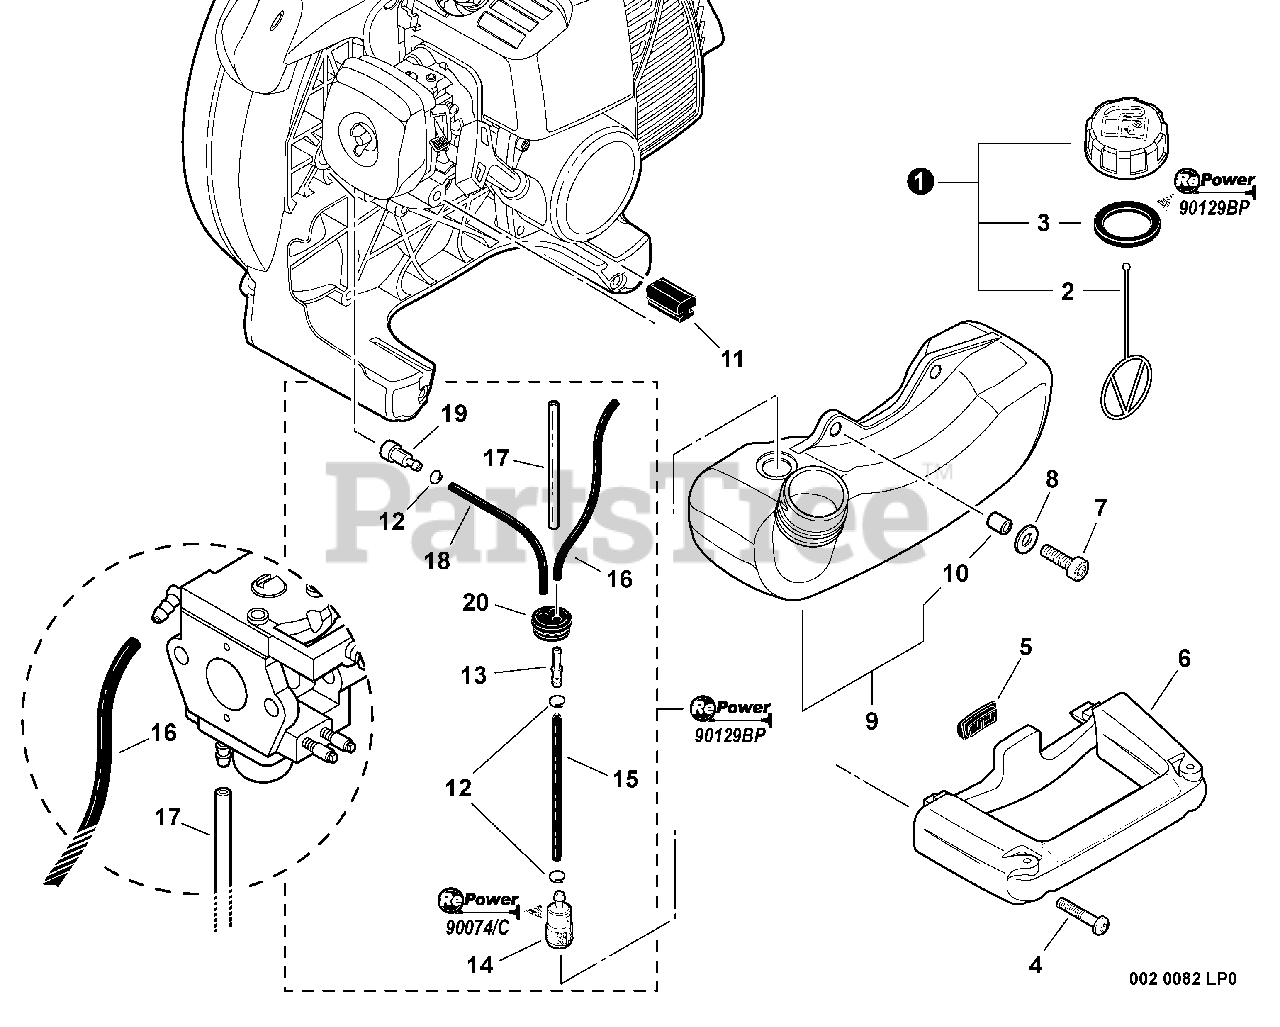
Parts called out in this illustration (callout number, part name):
1	CAP ASSY, FUEL
2	CONNECTOR, CAP L= 100 MM
3	GASKET, FUEL CAP
4	BOLT, TORX 5×25
5	CUSHION
6	HANDLE, REAR
7	BOLT, TORX 5×16
8	WASHER 5.5×12×0.8
9	TANK ASSY, FUEL
10	SPACER 6.2×7.8×6
12	CLIP Ø6
13	CONNECTOR, PIPE Ø5ר3.5
14	FILTER, FUEL
15	PIPE, FUEL 3×5×130 BLACK
16	PIPE, FUEL 3×5×78 BLACK
17	PIPE, FUEL 3×6×85 CLEAR
18	PIPE, FUEL 3×5×80 BLACK
19	VENT ASSY
20	GROMMET, FUEL Ø5
21	FUEL SYSTEM KIT
22	TUNE-UP KIT - REPOWER
